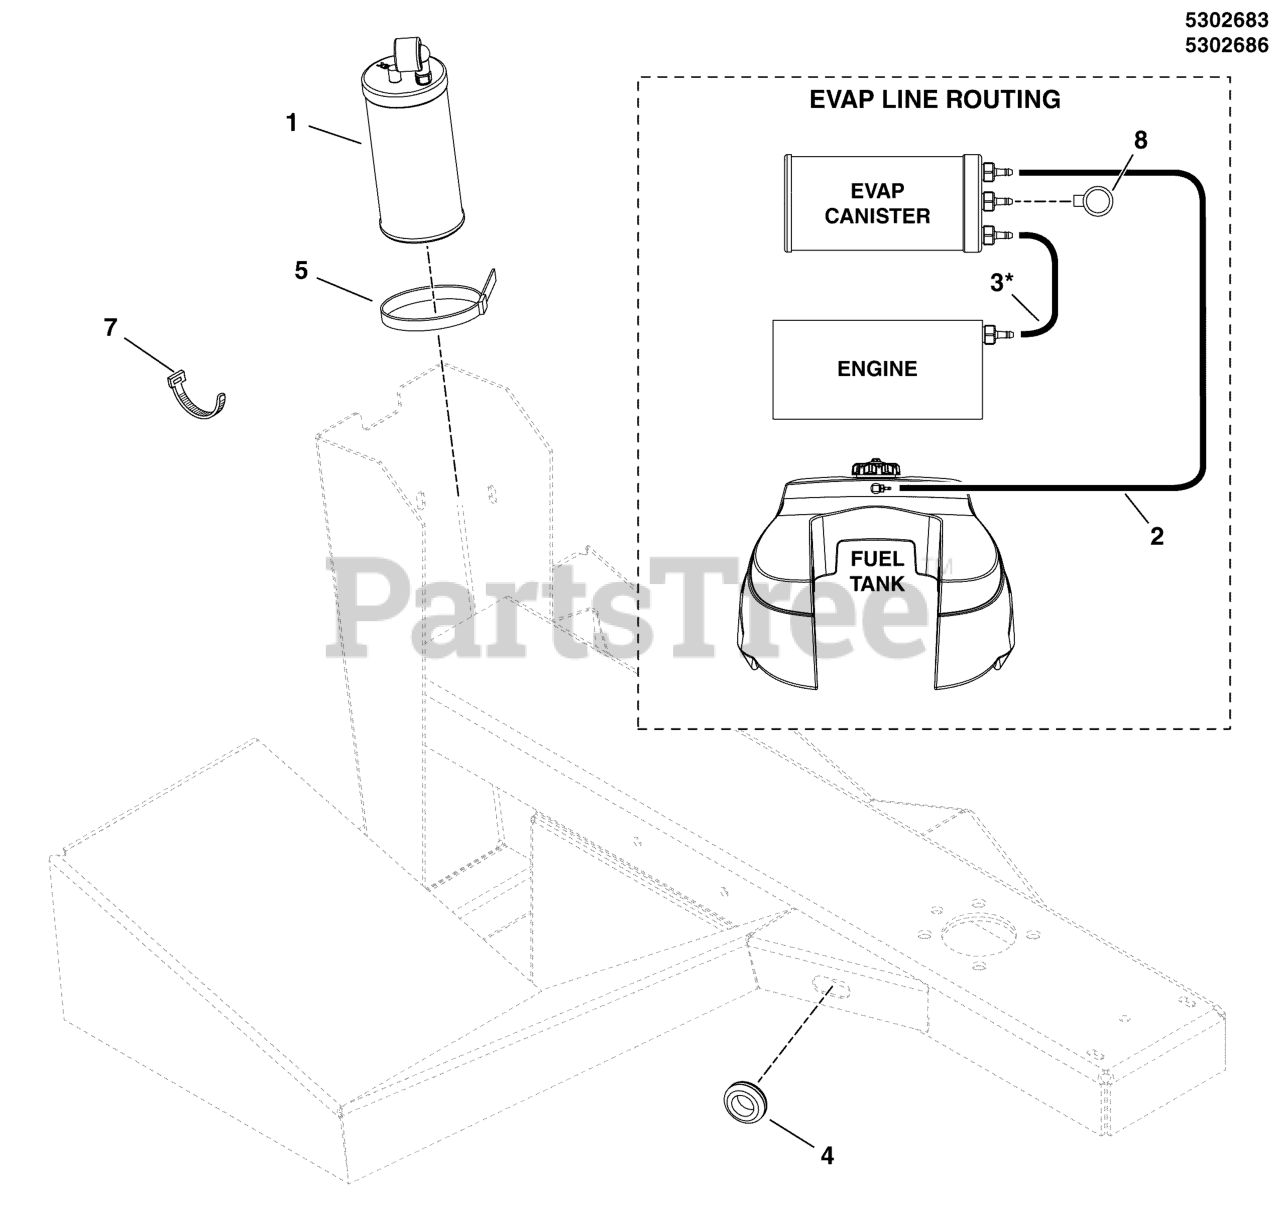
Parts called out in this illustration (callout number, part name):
1	CNSTR, CARB, 6 GAL
2	HOSE, VAPOR, 5MM ID, 73.50 LG
4	GROMMET, 7/8
5	TIE,SELF-LOCKING, 24"
6	DECAL, EPA CERT, ZTRS
7	CABLE TIE, 12
8	DUST FILTER, CANISTER (SV)
